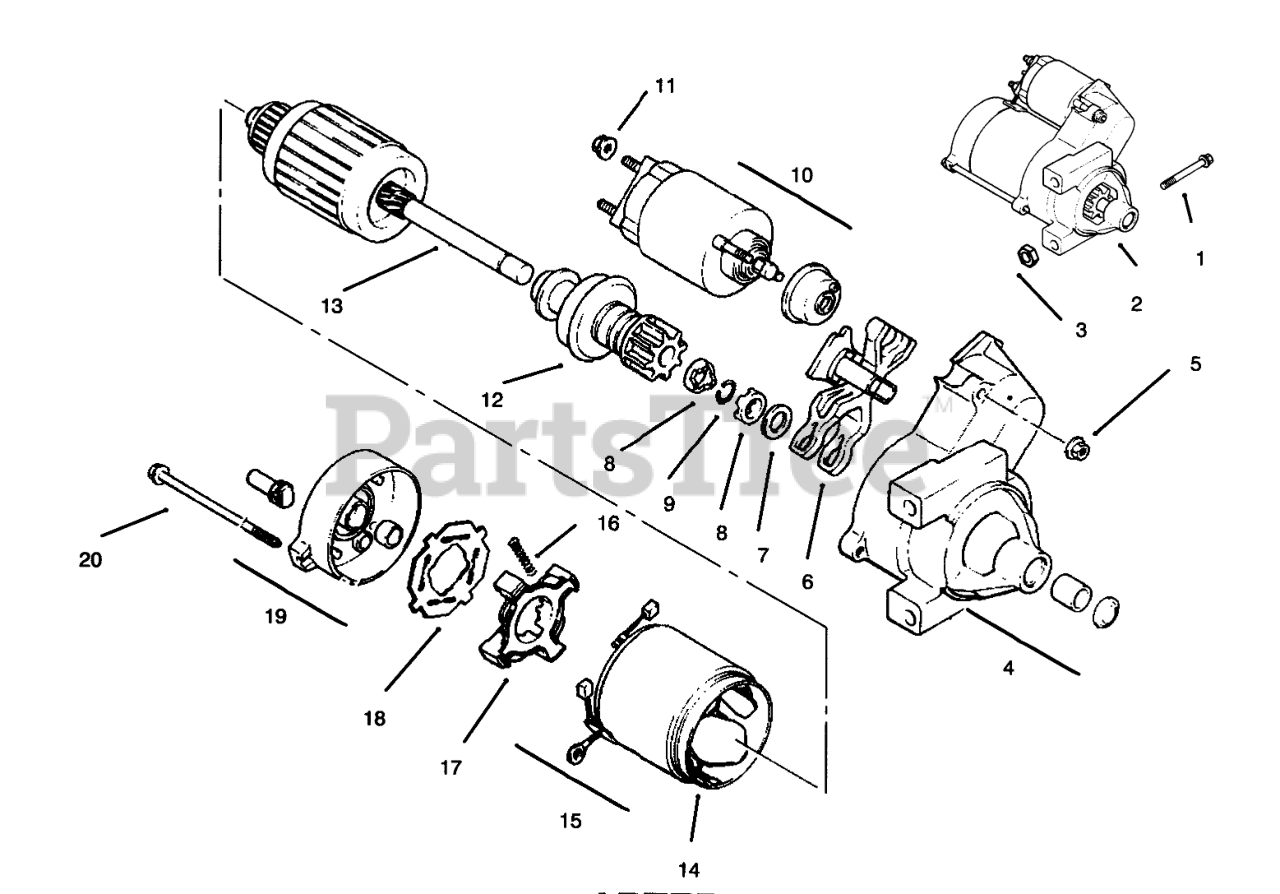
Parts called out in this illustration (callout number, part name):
2	Starter-Solenoid Shift (Incl. Ref. #4-20)
4	Cap-Drive End
5	Nut Starter
6	Lever Starter Drive
7	Washer-Thrust
8	Nut-Stop Collar
9	Ring-Retainer
10	Solenoid
12	Drive-Pinion
13	Armature-Starter
15	Kit-Brush (Incl. Ref. #16)
16	Spring-Brush
17	Holder-Brush
18	Insulator
19	Cap-Commutator End
